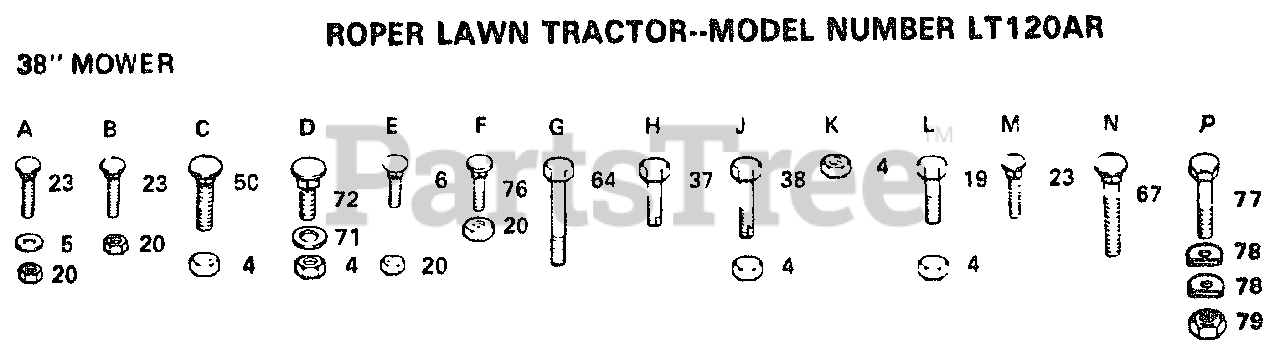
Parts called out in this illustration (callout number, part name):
5	WASHER M
6	BOLT
23	BOLT
37	SCREW
38	SCREW
50	BOLT
67	BOLT.3/8-14X1.25
71	WASHER
72	BOLT
78	WASHER T
